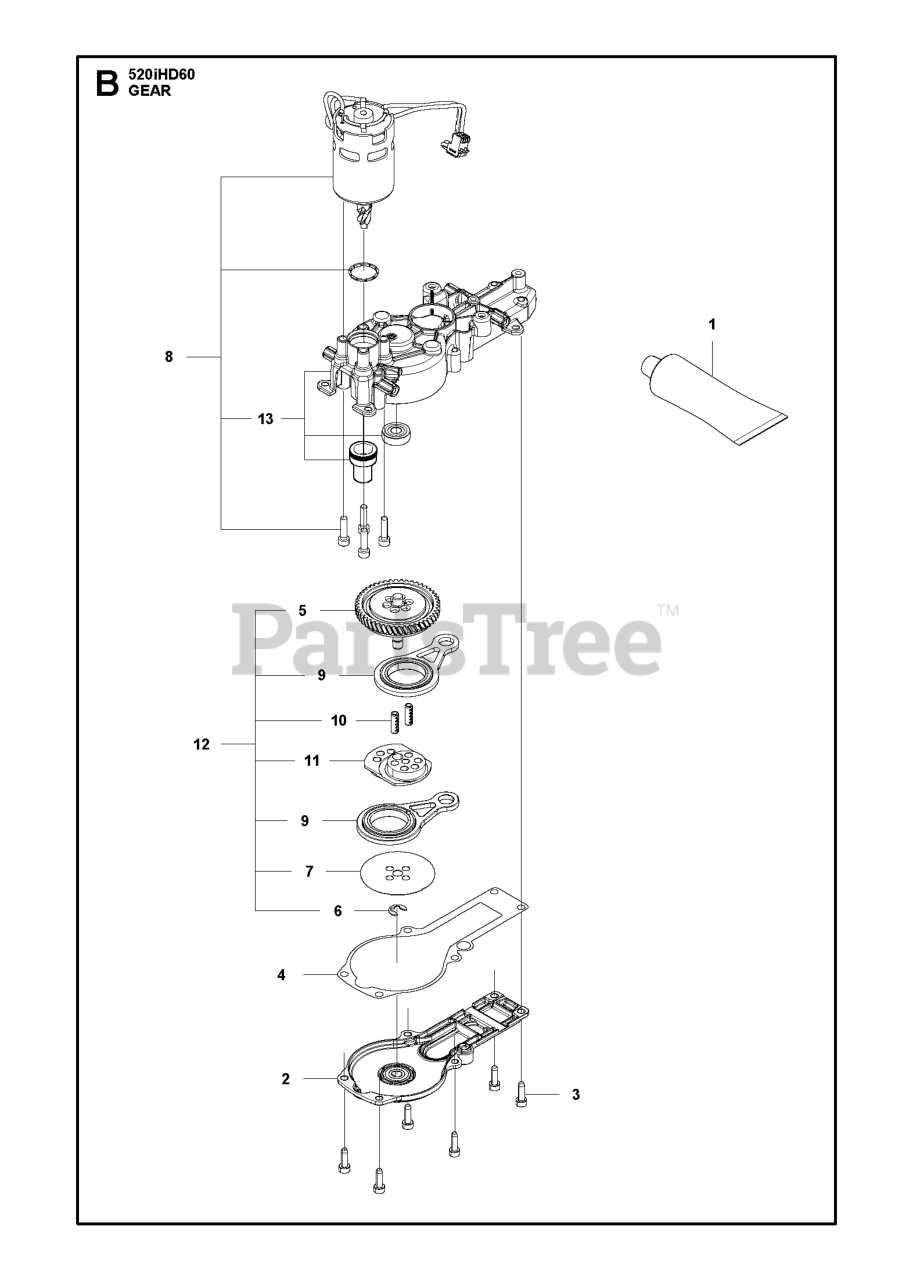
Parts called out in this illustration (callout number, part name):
1	GREASE 20G HEDGE TRIMMER GEAR
3	SCREW IHSCFT
5	HELICAL GEAR CPL DC
6	LOCK WASHER
7	WASHER DISK DISC
8	MOTOR ASSY MOTOR-GEARBOX ASSY
9	CONNECTING ROD ASSY
10	HEAVY DUTY DOWEL PIN PROJEKT 1
11	ECCENTRIC DISC
12	GEAR HELICAL KIT 536LIHD60X/ 5
13	GEAR CASE ASSY DC
